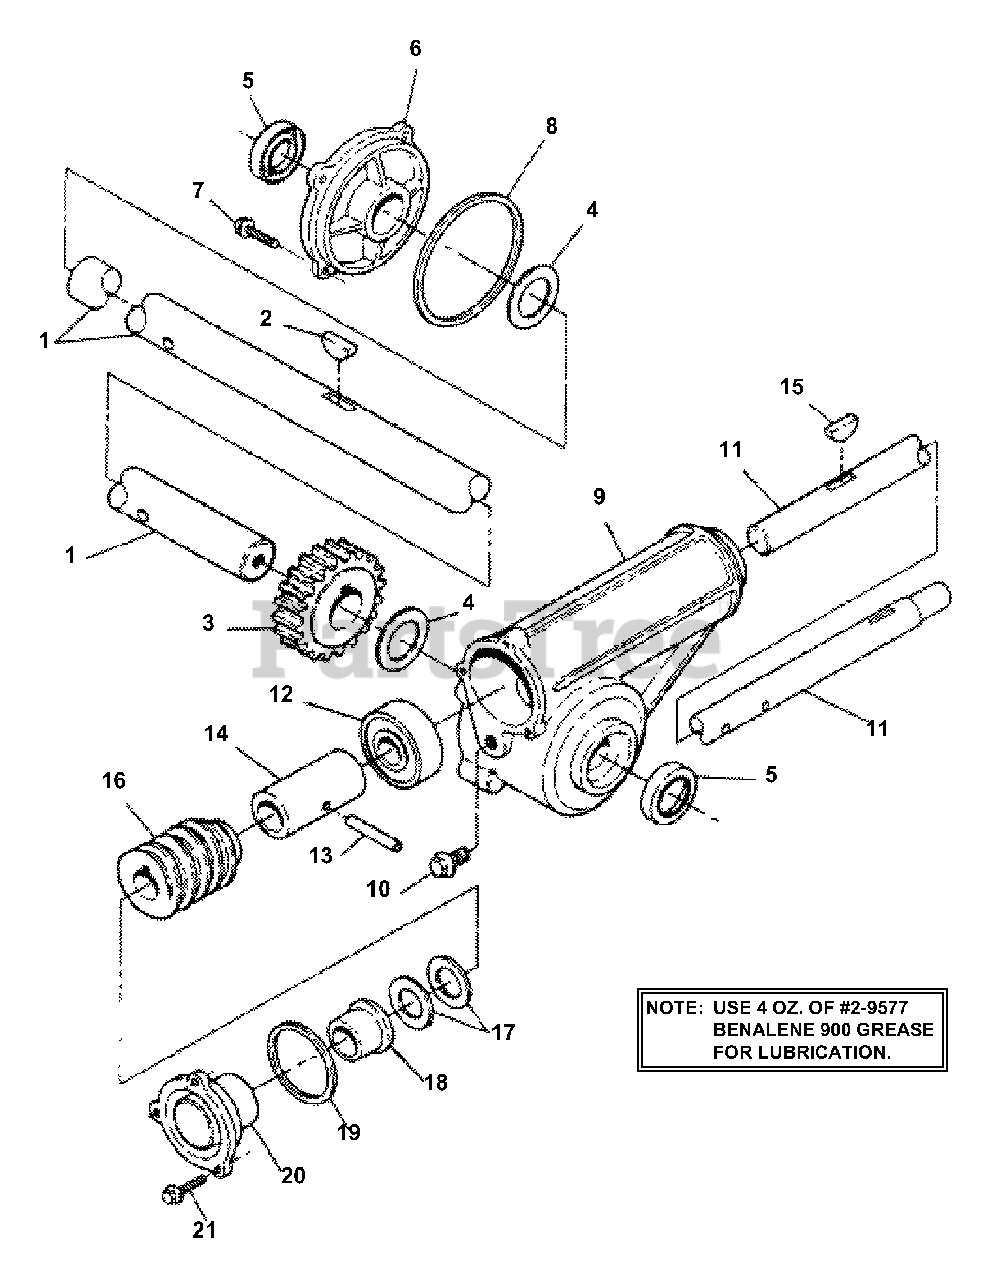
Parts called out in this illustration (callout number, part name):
1	SHAFT, Auger
2	KEY, 1/4 x 7/8" Woodruff
3	GEAR, Worm
4	WASHER, 1.0 x 1-1/2" Thrust
5	SEAL, 1-1/2" O.D. Oil
6	COVER, Gear Case
7	SCREW, 1/4-20 x 3/4" Hex Washer Self-Tap
8	O-RING, Case Cover
9	CASE, Gear
10	SCREW, 3/8-16 x 1/2" Hex Washer Self-Tap
11	SHAFT, Impeller
12	BEARING, Impeller Shaft
13	PIN, 1/4 x 1-1/2" Roll
14	SPACER, Gear Bearing
15	KEY, 3/16 x 7/8" Woodruff
16	GEAR, Rolled Worm
17	WASHER, 3/4 x 1-1/8" Thrust
18	BUSHING, Impeller Shaft
19	O-RING, Case Cap
20	CAP, Case
21	SCREW, #10-24 x 5/8" Hex Washer Self-Tap
